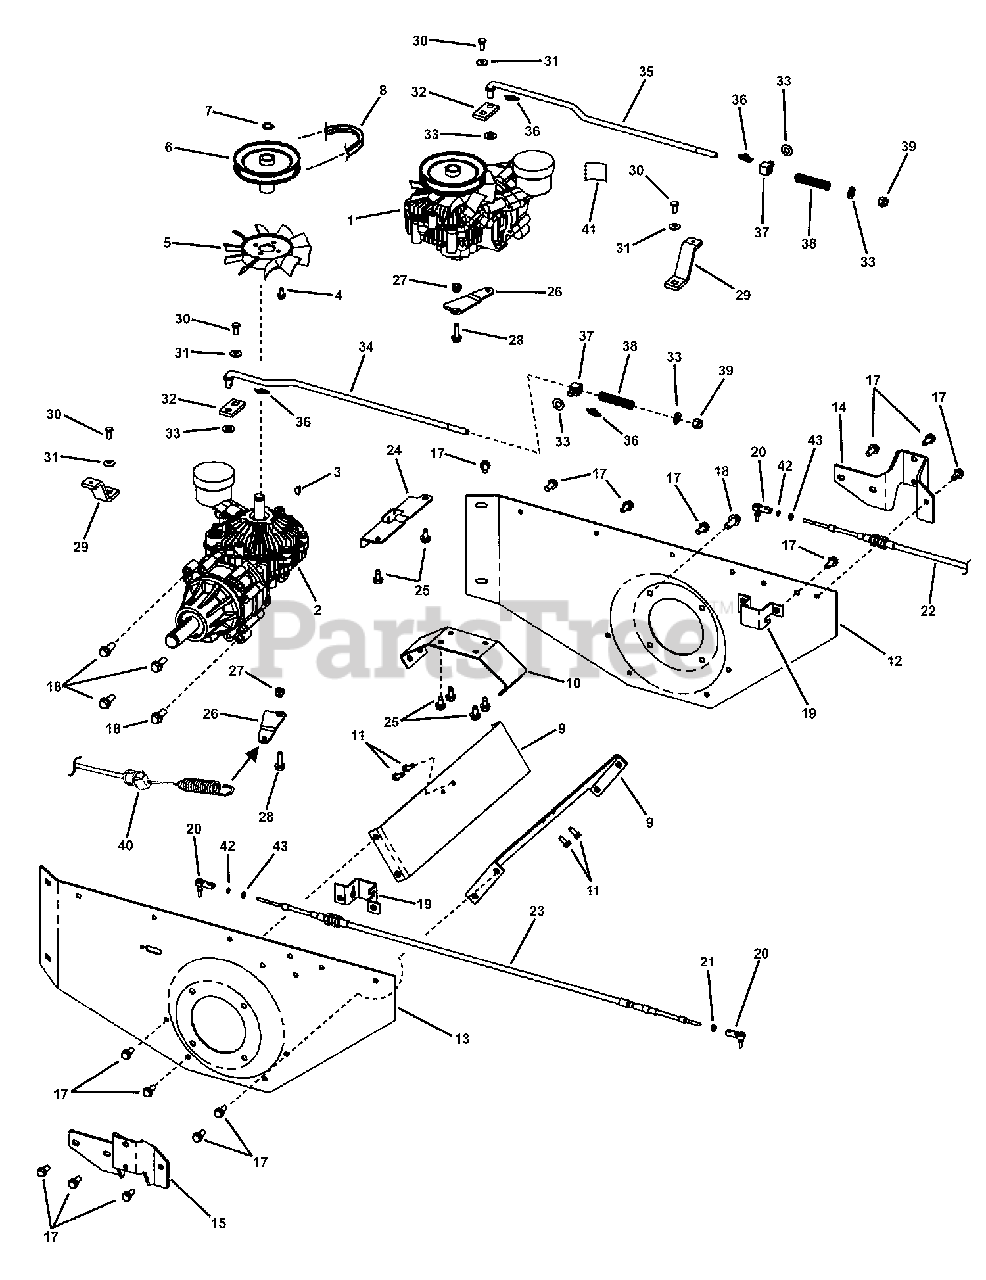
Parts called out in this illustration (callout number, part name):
1	TRANSAXLE, Hydro
2	TRANSAXLE, Hydro w/o Manifold R.H.
3	KEY, #605 Woodruff
4	SCREW, 1/4-20 x 1/2" Hex Washer Self-Tap
5	FAN, 6" O.D., 10 Blade
6	PULLEY, Hydro Input
7	RING, RR3100-66 External Retaining
8	V-BELT, HA Sect. 42.00" effective length
9	BRACKET, Support, Fender
10	BRACKET, Support, Hydro
11	SCREW, 1/4-20 x 5/8" Hex Washer Self-Tap
12	FENDER, Rear Frame, Left Hand
13	FENDER, Rear Frame, Right Hand
14	BRACKET, Deck Support, Left Rear
15	BRACKET, Deck Support, Right Rear
17	SCREW, 5/16-18 x 3/4" Hex Washer Self-Tap
18	SCREW, 3/8-16 x 1" Hex Washer Self-tap
19	BRACKET, Control Cable, Hydro
20	ROD END, #10-32 w/Stud
21	NUT, #10-32 Hex Center Lock
22	CABLE, L.H. Hydraulic Control (45.5" long)
23	CABLE, R.H. Hydraulic Control (35.0" long)
24	BRACKET, Cable, Hydro Release Valve
25	SCREW, 5/16-18 x 5/8" Hex Washer Self-Tap
26	BRACKET, Actuator, Hydro Release Valve
27	BUSHING, Differential Link, Powdered Metal
28	SCREW, 5/16-18 x 1" Hex Washer Self-Tap, GR 5
29	ARM, Directional Control
30	BOLT, 1/4-28 x 5/8" w/Nyloc Patch, GR 8
31	WASHER, 1/4" Belleville
32	ARM, Brake
33	WASHER, 3/8" Flat
34	ROD, Brake, R.H.
35	ROD, Brake, L.H.
36	COTTER-PIN, 1/16" x 1.42" Self-Locking
37	SWIVEL, Brake Link- PM
38	SPRING, Brake Compression
39	NUT, 3/8-16 Hex Nyloc
40	CABLE, Hydro Release Valve
41	DECAL, Hydro Reservoir
42	WASHER, #10, Internal Tooth Lock
43	NUT, #10-32, Hex
